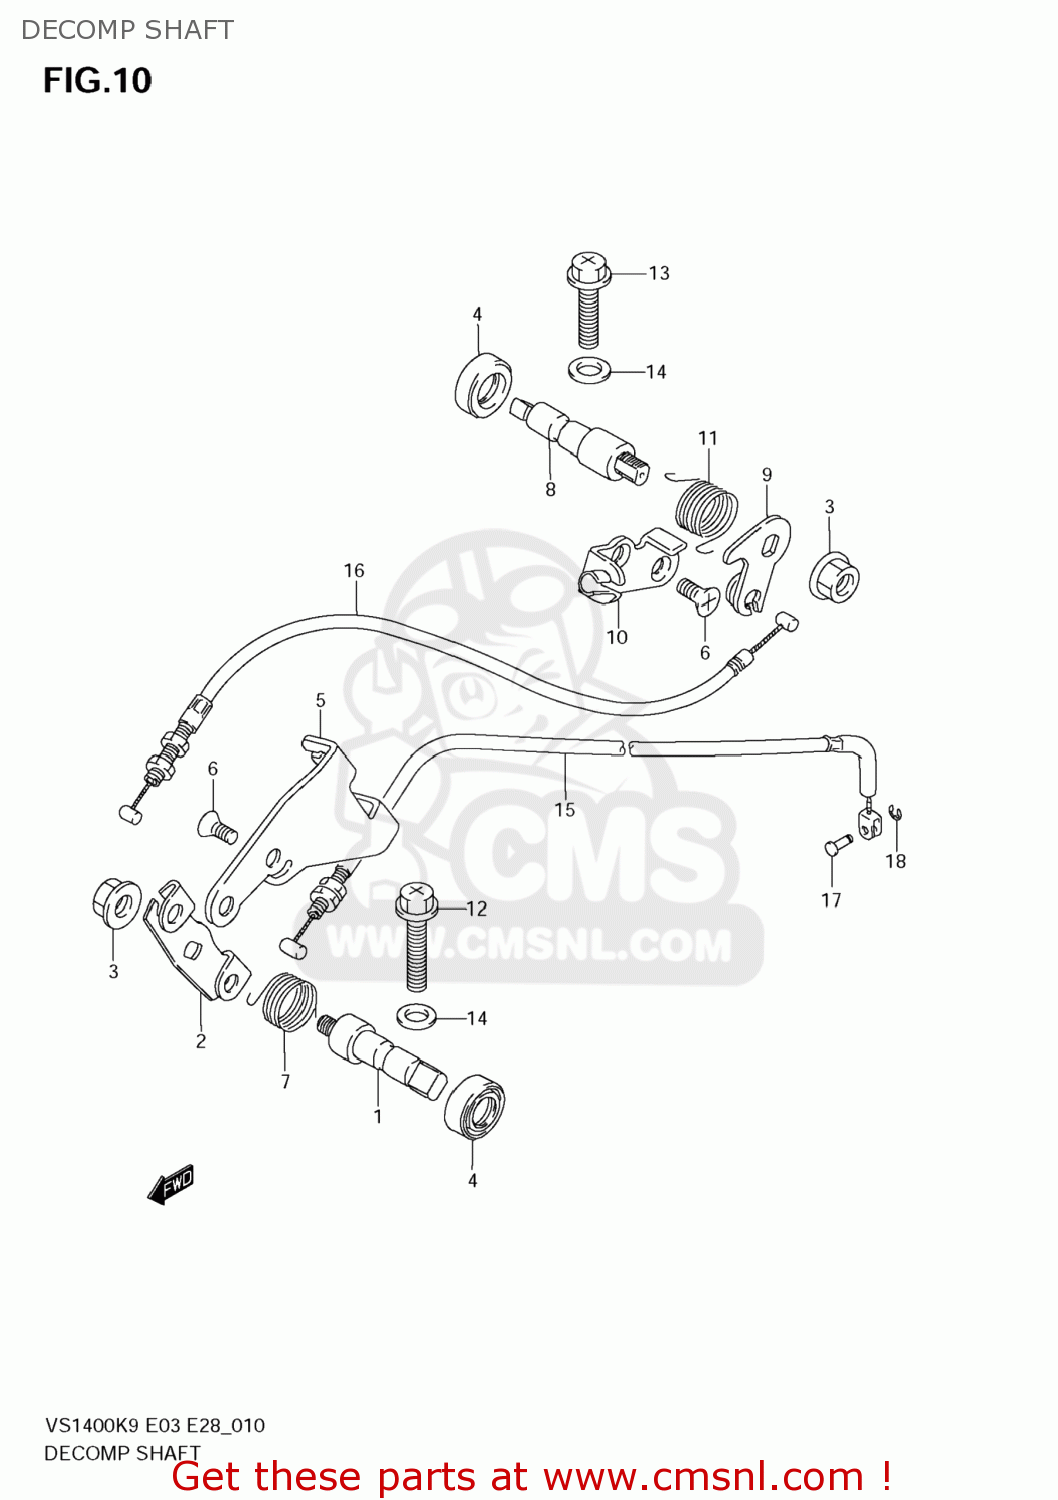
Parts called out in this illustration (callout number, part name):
1	SHAFT,DECOMP FR
2	LEVER,DECOMP SHAFT FR
3	NUT
4	SEAL,OIL(10X20X6)
5	HOLDER,DECOMP CABLE FR
6	SCREW
7	SPRING
8	SHAFT,DECOMP RR
9	LEVER,DECOMP SHAFT RR
10	HOLDER,DECOMP CABLE RR
11	SPRING
12	SCREW
13	SCREW
14	GASKET(5.8X13X1.2) (NAS)
15	CABLE ASSY,DECOMP FR
16	CABLE ASSY,DECOMP RR
17	PIN(4X12.5)
18	E RING
